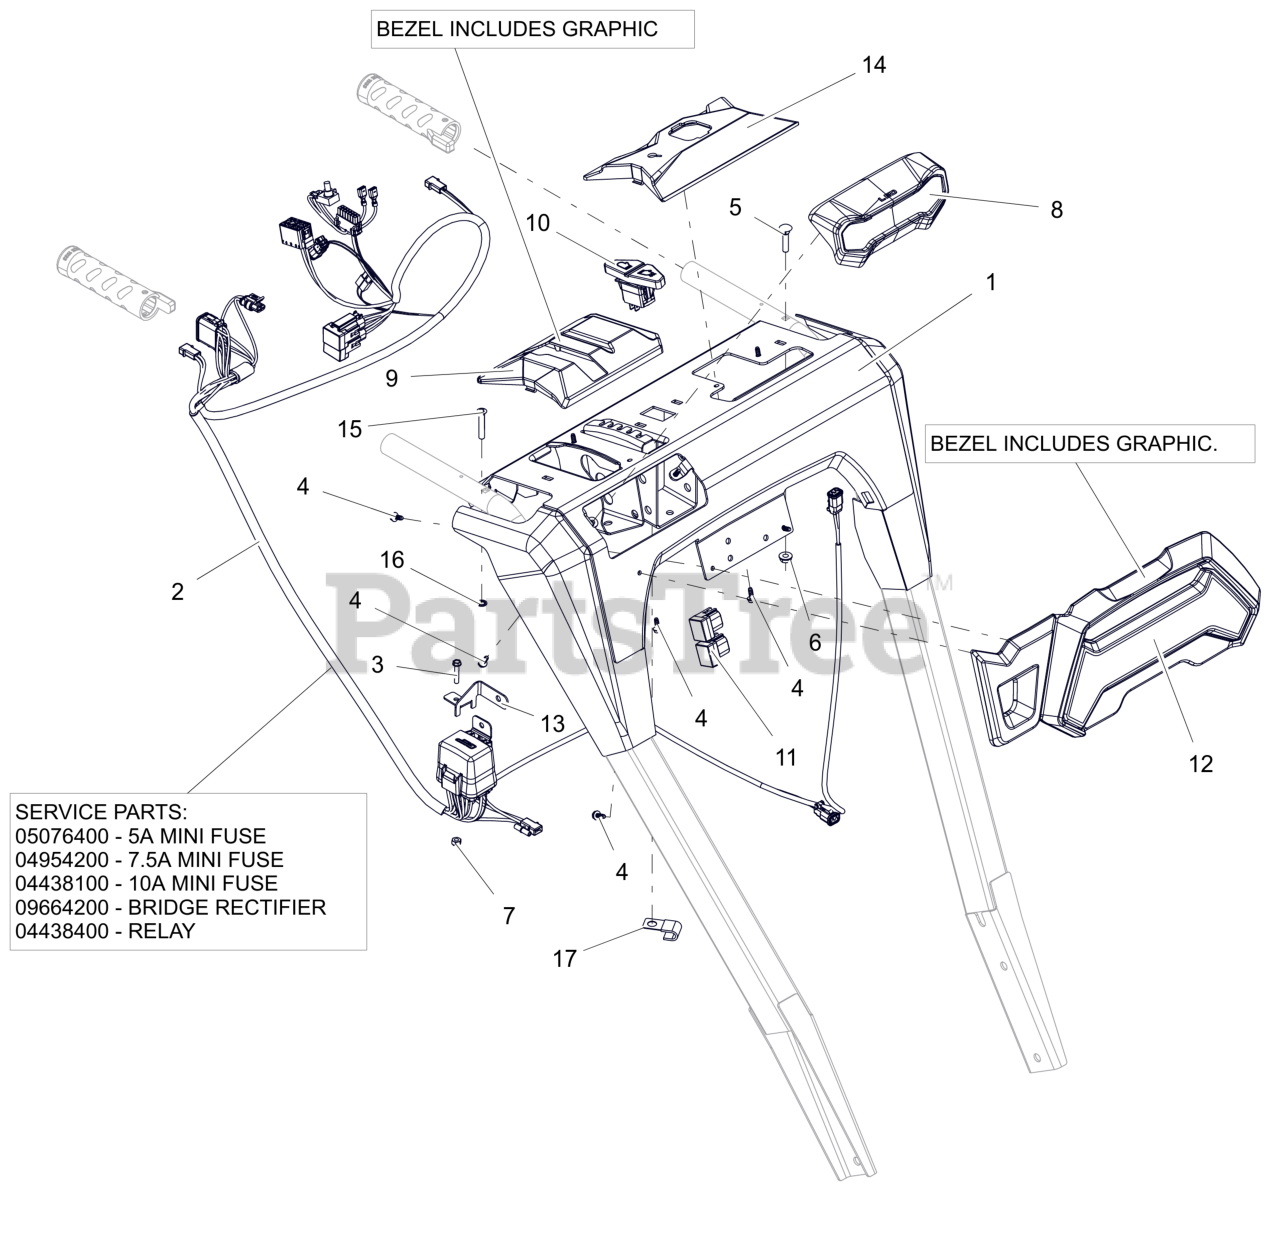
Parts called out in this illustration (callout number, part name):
1	PANEL, DASH HYDRO EFI ECR TRACK
2	HARNESS-WIRE- LT HG EFI ECHUTE
2	FUSE, 5 AMP MINI-ATC
2	FUSE, 7.5 AMP MINI-ATC
2	FUSE,10 AMP MINI-ATC
2	RECTIFIER, BRIDGE
2	RELAY,MICRO5 TERML W/RESISTOR
3	BLT, HWH #10-24X1.00 ZCC
4	SCR, PLASTIC #10X.50
5	BLT-RDHDXLSQNK.25-20X1.25 G5ZC
6	NUT-LK-CTR-FLG .25-20 ZC120
7	NUT-LK-NYL #10-24 G2 ZCC
8	HEADLIGHT ASM- LED
9	BEZEL, SHIFT HYDRO TRACK DECAL
10	SWITCH- ROCKER SPST-ON/OFF
11	PACK, DIODE
12	BEZEL- LARGE - PROFESSIONAL
13	BRKT, MOUNT RECTIFIER
14	BEZEL, OPERATOR EFI DECAL
15	SCR,OVAL .25-20X1.50 ZCC
16	WSHR-LK-INT .250 TH TYA
17	J-CLAMP
